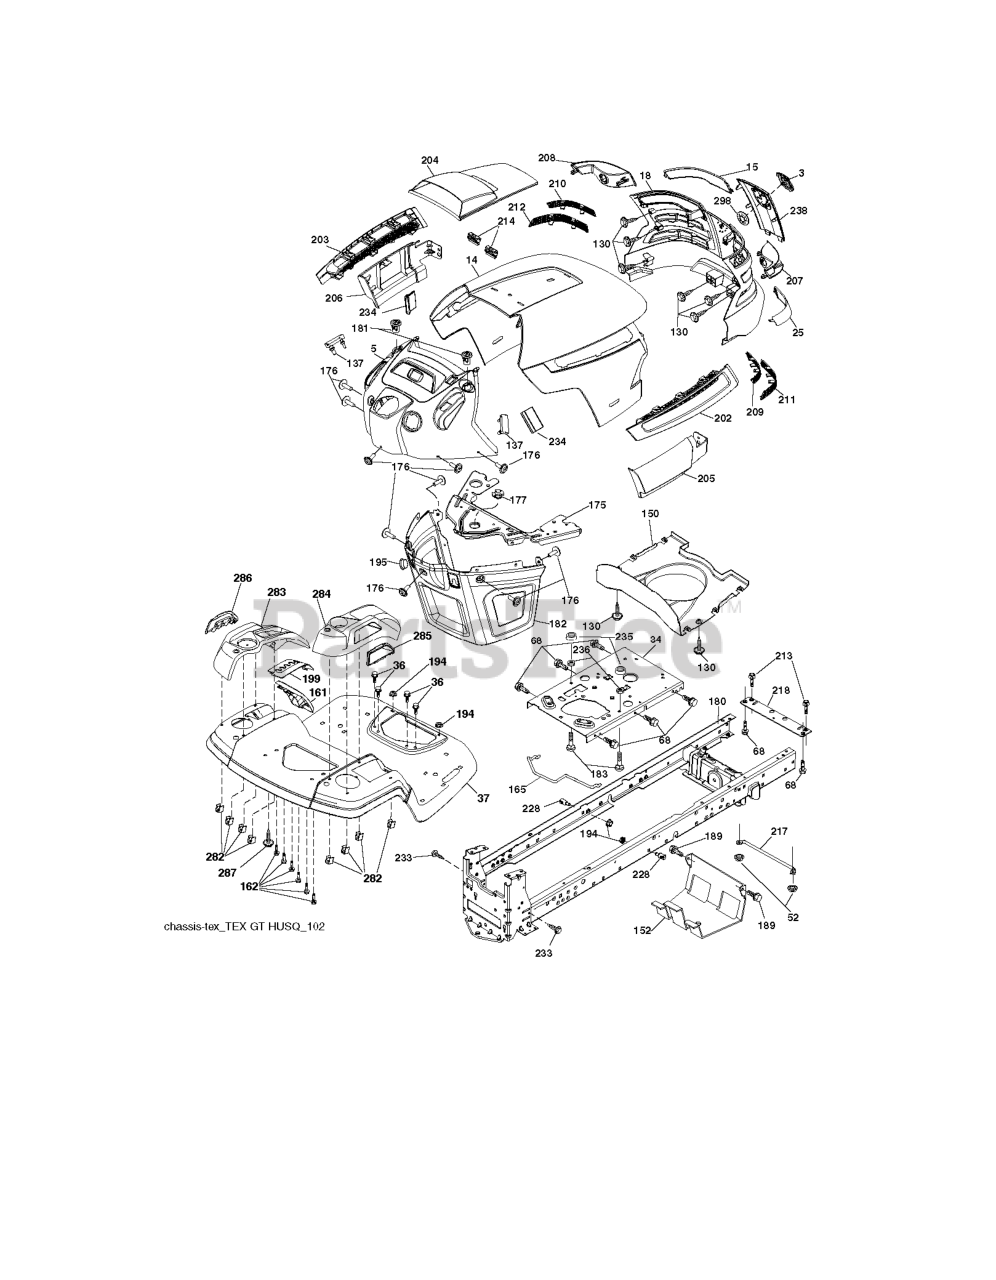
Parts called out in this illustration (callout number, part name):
3	RP LOGO
14	HOOD
15	LENS.LH.TEX.GT.HUSQ.CL
18	GRILL.ASM.HUSQ.TG/CRD.W/TRIM
25	LENS.RH.TEX.GT.HUSQ.CL
34	PLATE.ENGINE.WELDED.CHASSIS
36	SCREW 5/16"
37	FENDER.TLT.FS.W/CPH/FW/RSF.ORN
52	LOCKNUT
68	Screw 5/16-18 x 1/2 Hex, Self Tapping 5/16-18 x 1/2
130	SCREW.#10 X 0.750.BOS
137	BUMPER DASH
150	AIR.DUCT.HOOD.TEX.GT.HUSQ
152	SHIELD.BROWNING.W/TEX
161	WINDOW FUEL
162	SCREW.HI-LO.CONSOLE
165	SUPPORT.TANK.REAR.W/TEX
175	PLATE.CROSSMEMBER.HUSQ
176	SCREW.#10-24X5/8.RN.QU
177	BUSHING, STEERING
180	CHASSIS
181	BUSHING.MNT.FEND.CRGO.
182	DASH.LOWER.COMMON.12V.ADAPTOR
183	BOLT.5/16-18X1-1/4 FULL THD
189	SCREW
194	NUT LOCK HEX FLANGE 5/16-18
195	PLUG.HOLE.DASH.LOWER.12V.BLK
199	PLATE.DECK.LIFT.HUSQ.LT
202	VENT.SIDE.HOOD.HUSQ.RH.GREY
203	VENT.SIDE.HOOD.HUSQ.LH.GRAY
204	HOOD VENT
205	SKIRT.HOOD.SIDE.HUSQ.RH.GREY
206	SKIRT.HOOD.SIDE.HUSQ.LH.GREY
207	BEZEL.RH.TEX.GT.HUSQ
208	BEZEL.LH.TEX.GT.HUSQ
209	INSERT.HEX.GRILL.HUSQ.GREY
210	INSERT.HEX.GRILL.HUSQ.
211	INSERT.HEX.GRILL.HUSQ.
212	INSERT.HEX.GRILL.HUSQ.
213	BOLT
214	CLIP.RETAINER.TINNER.
217	ROD.PIVOT.HOOD
218	X-PIECE.HOOD.STOP.NON/
228	STUD.FASTNER.W/ANTI-ROTATE
233	BOLT.SHOULDER
234	BUMPER.HOOD.TEX.HUSQVARNA
235	SPACER FENDER
236	NUT.CENTERLOCK.5/16-
238	TRIM.HUSQ.TG/CRD.SERVICE
282	CLIP.RETAINER.CONSOLE.LT.HUSQ
283	CONSOLE.DECK.LFT.R.SDFL.HUSQLT
284	CONSOLE.CNTRL.
285	CONSOLE INSERT RH
286	CONSOLE.INSRT.LH.HUSQ.LT.BLACK
287	SCREW 1/4X20
